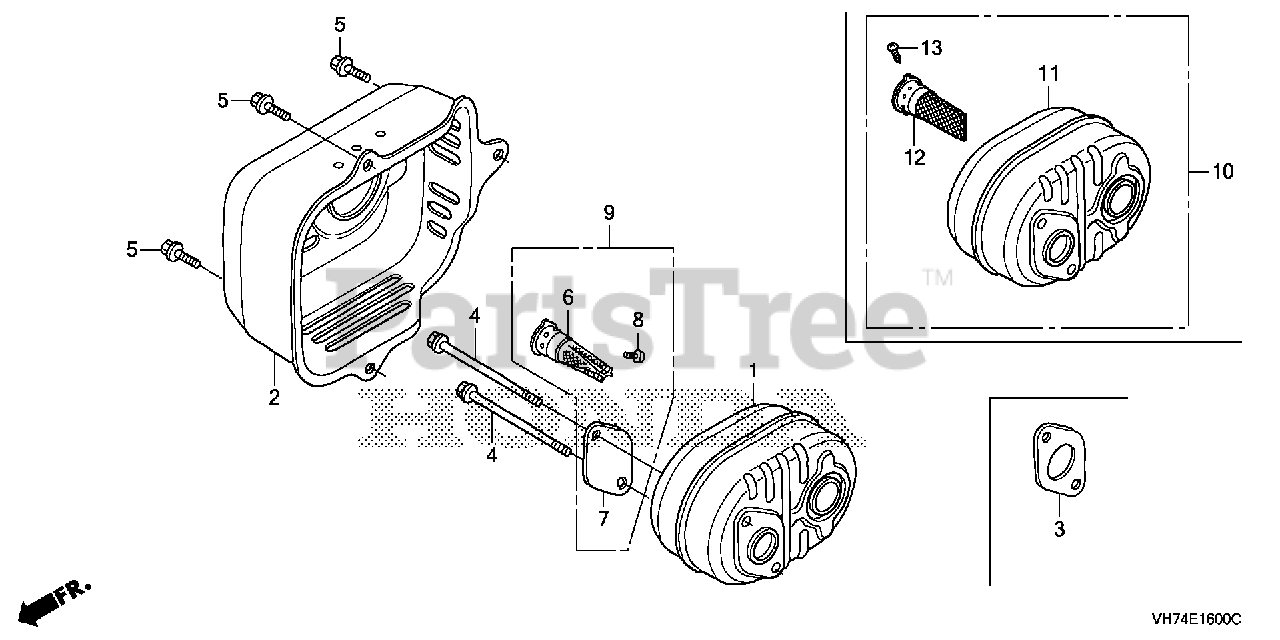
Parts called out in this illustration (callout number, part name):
2	PROTECTOR, MUFFLER
3	GASKET, MUFFLER
4	BOLT, FLANGE (6X79) (CT200)
5	BOLT, FLANGE (6X12) (CT200)
6	ARRESTER, SPARK (TO 1207644)
7	PLATE, ARRESTER NUMBER (TO INSTALL OPTIONAL SPARK ARRESTER)
8	SCREW, TAPPING (4X6) (TO INSTALL OPTIONAL SPARK ARRESTER)
9	ARRESTER KIT, SPARK
10	MUFFLER ASSY. (ARRESTER)
11	MUFFLER
12	ARRESTER, SPARK
13	SCREW, TAPPING (4X6) (TO INSTALL OPTIONAL SPARK ARRESTER)
